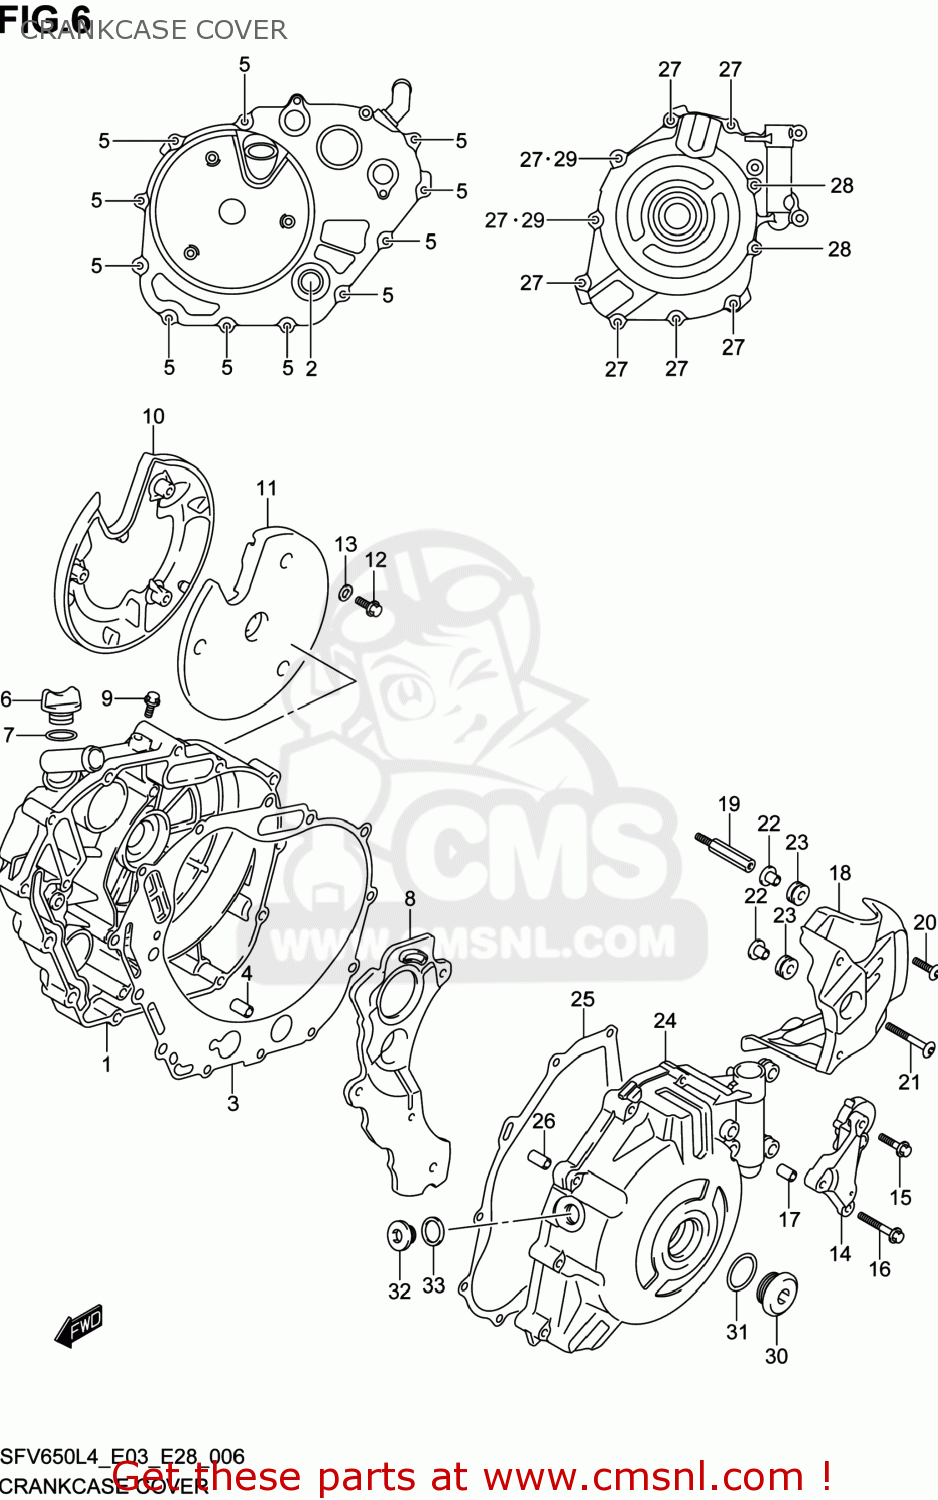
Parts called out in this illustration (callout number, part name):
1	COVER,CLUTCH
2	LENS,OIL LEVEL CHECK
3	GASKET,CLUTCH COVER (NAS)
4	PIN
5	BOLT(6X35)
6	PLUG,ENGINE OIL FILLER
7	O RING(D:3.1,ID:16.8)
8	SEPARATOR,OIL
9	BOLT(6X12)
10	COVER,CLUTCH OUTER
11	DAMPER,CLUTCH OUTER COVER
12	BOLT(6X16)
13	GASKET(5.8X13X1.2) (NAS)
14	COVER,ENGINE SPROCKET INNER
15	BOLT
16	BOLT
17	PIN
18	COVER,ENGINE SPROCKET OUTER
19	BOLT,SEC DRIVE UNIT COVER
20	SCREW(6X20)
21	SCREW(6X40)
22	WASHER
23	CUSHION
24	COVER,MAGNETO
25	GASKET,MAGNETO COVER (NAS)
26	PIN
27	BOLT(6X35)
28	BOLT(6X65)
29	GASKET(5.8X13X1.2) (NAS)
30	PLUG(26X9)
31	O RING(D:3.1,ID:22.7)
32	PLUG,16X8
33	GASKET(16X22X2) (NAS)
